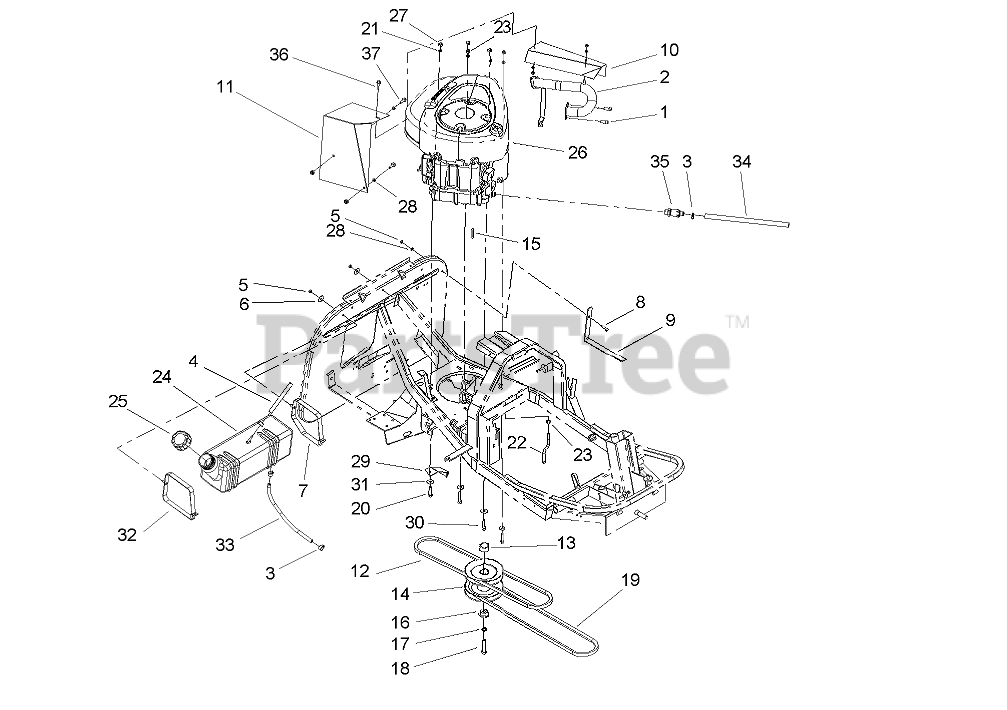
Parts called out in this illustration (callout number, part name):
1	SCREW-HSH
2	PIPE-EXHAUST
3	CLAMP-TUBE
4	Hose-Fuel
5	NUT-LOCK
6	Washer-Flat
7	STRAP-FUEL TANK, LEFT
8	SCREW-HH
9	Guard-Muffler
10	SHIELD-PIPE, EXHAUST
11	SHIELD-MUFFLER, REAR
13	Spacer
14	PULLEY
15	KEY-SQUARE
16	Spacer
17	Washer-Lock
18	SCREW-HH
19	BELT-DECK
20	SCREW-HH
21	WASHER-PLAIN
22	Guide-Belt
23	NUT-HEX
24	TANK-FUEL
25	GAS CAP ASM
26	ENGINE ASM
27	NUT-LOCK
28	WASHER-FLAT
29	BRACKET, DRIVE BELT
30	Screw-HH
31	Washer-Flat
32	STRAP-FUEL TANK, RIGHT
33	Hose-Fuel
34	TUBE-DRAIN, OIL
35	VALVE-DRAIN, OIL
36	SCREW-HHF
37	SCREW-HHF
